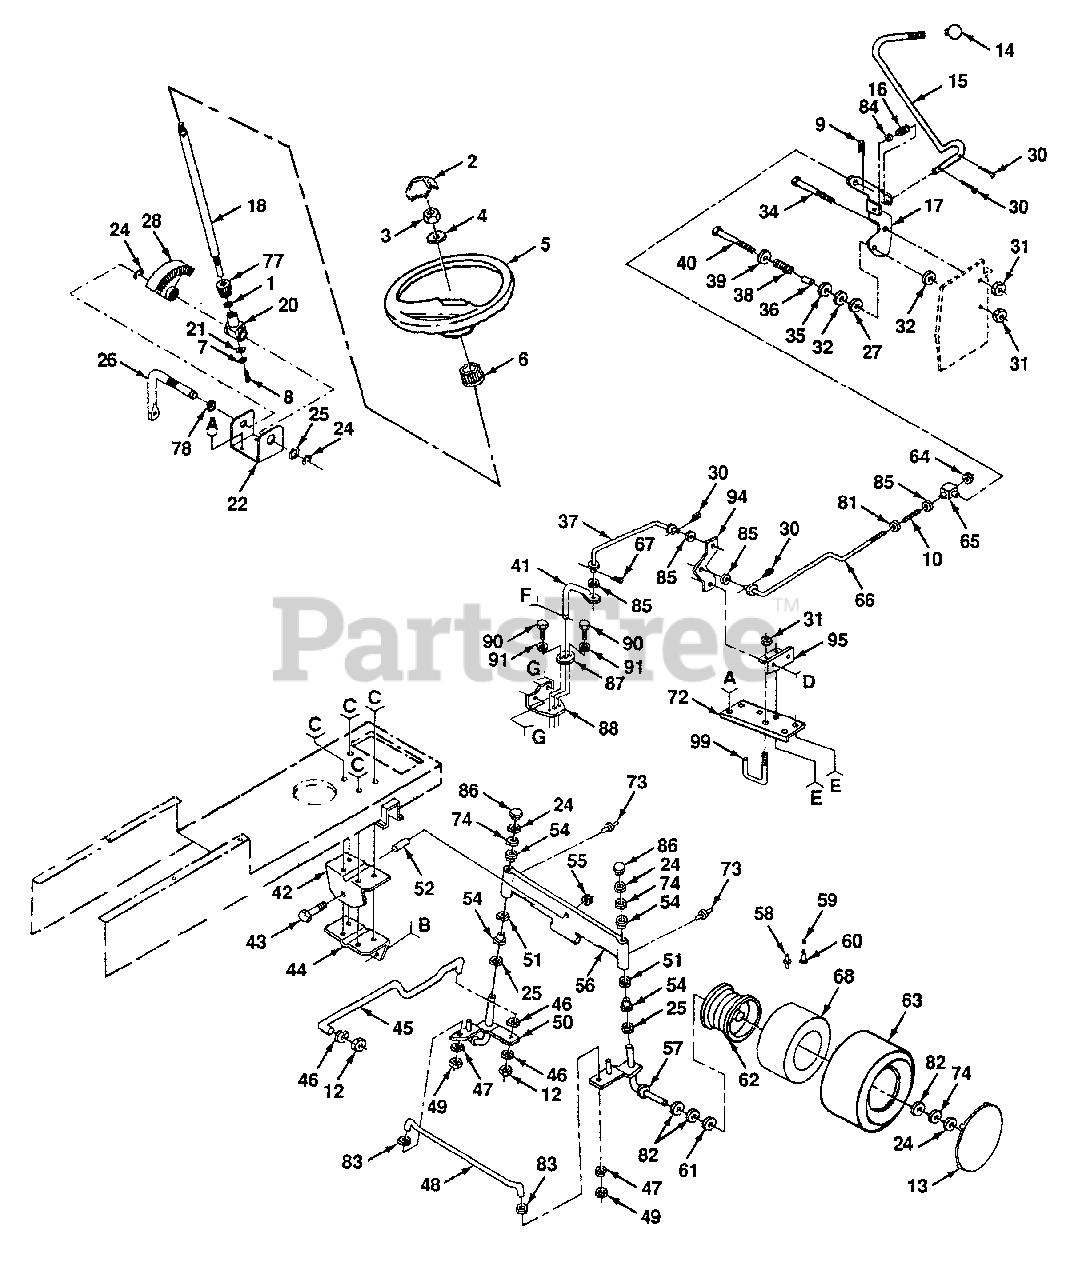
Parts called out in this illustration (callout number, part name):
2	Insert, Steering Wheel
3	Nut, Jam, Toplock 1/2 - 20
5	Wheel, Steering
6	Adapter, Steering Wheel
7	Washer, Lock 1/4
8	Screw, Socket, Hex 1/4 - 20 x 5/8
9	Spring, Retainer
10	Spring, Compression
12	Nut, Fin, Hex 3/8 - 24 UNF
13	Cover, Wheel
14	Knob, Gearshift
15	Rod, Control
16	Spring, Torsion
17	Bracket, Control Rod
18	Shaft, Steering
20	Support, Shaft
21	Washer, Shim 1/4 x 5/8 x .062
22	Bracket, Steering
25	Bearing, Thrust
26	Shaft, Pitman
27	Washer, Phenolic
28	Gear, Sector
30	Pin, Cotter 1/8 x 3/4
31	Nut, Crownlock 3/8 - 16
32	Washer, Friction
34	Bolt, Hex, Shoulder 3/8 - 16 x 1-3/8
35	Washer 21/32 x 1-1/4 x 16 Gauge
37	Link, Control, Pump
38	Spring, Compression
39	Washer 13/32 x 1-1/4 x 12 Gauge
40	Bolt, Hex 3/8 - 16 x 3
41	Lever, Pump Control
42	Support, Saddle, Rear
43	Bolt, Hex 5/8 - 11 x 3-3/4
44	Support, Saddle, Front
45	Link, Drag
46	Washer, Lock 3/8
47	Washer, Lock 5/16
48	Rod, Tie
49	Nut, Hex 5/16 - 24 UNF
50	Spindle, L.H.
51	Washer 27/32 x 1-1/4 x 16 Gauge
52	Spacer, Bearing
55	Locknut, Flange 5/8 - 11
56	Axle, Front
57	Spindle, R.H.
58	Fitting, Grease
59	Stem, Valve
60	Cap, Valve
62	Rim, Front, 6"
63	Tire, Front
64	Locknut, Hex w/Washer Insert 3/8 - 16 UNC
66	Rod, Control, Adjustable
67	Clip, Hairpin
68	Tube
72	Bracket, Chassis, Reinforcement, Hydro
73	Fitting, Grease
74	Washer 25/32 x 1-5/8 x 16 Gauge
77	Gear, Pinion
78	Nyliner, Snap-In
81	Washer 13/32 x 3/4 x 12 Gauge
82	Washer 25/32 x 1-1/4 x 16 Gauge
83	Washer 11/32 x 3/4 x 16 Gauge
84	Washer 15/32 x 15/16 x 16 Gauge
85	Washer, Spring
86	Cap, Spindle
87	Guide, Control
88	Bracket, Control Guide
90	Screw, Tap, Hex #10-24 UNC x 1/2
91	Washer 7/32 x 1/2 x 16 Gauge
95	Bracket, Bellcrank Pivot
99	Keeper, Centerspan
